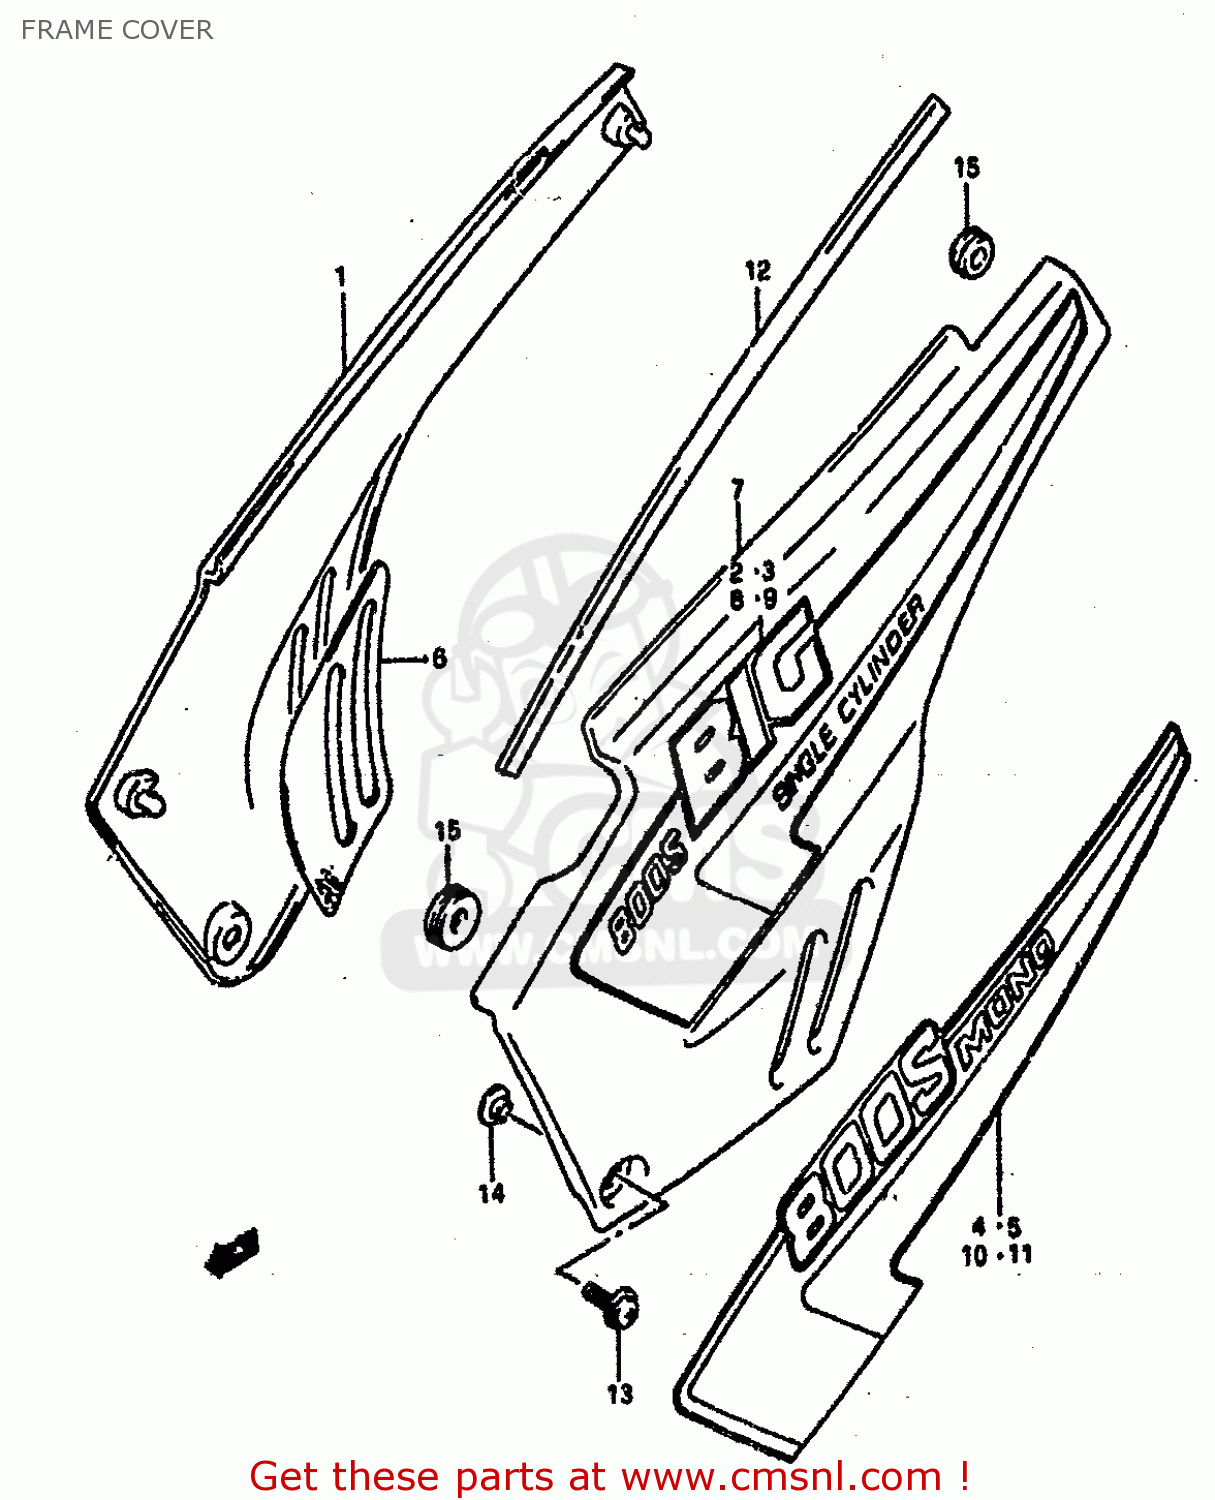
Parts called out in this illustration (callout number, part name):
1	COVER,FRAME R.
2	TAPE,RH
3	TAPE,RH
4	TAPE,RH
5	TAPE,RH
6	HEAT SHIELD,RH
7	COVER,FRAME,L(RED)
8	TAPE,LH
9	TAPE,LH
10	TAPE,LH
11	TAPE,LH
12	DUST SEAL,FRAME COVER
13	SCREW(6X20)
14	WASHER
15	CUSHION
16	CUSHION
